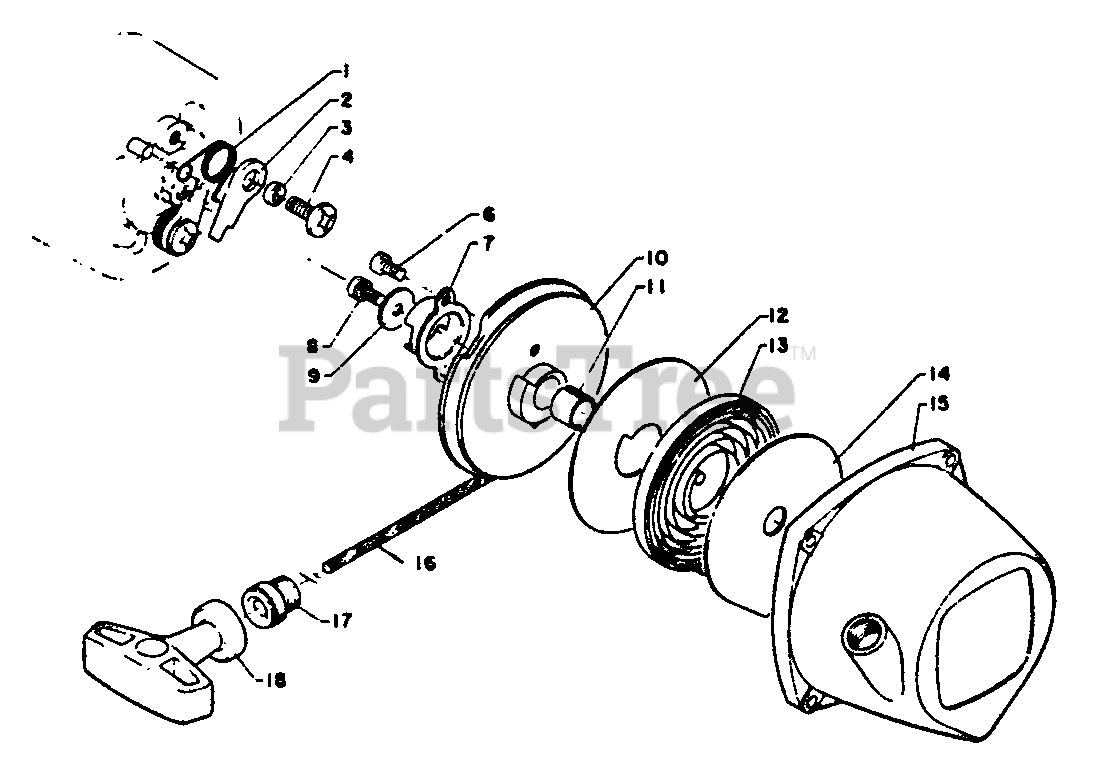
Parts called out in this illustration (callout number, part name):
1	SPRING, RETURN
2	PAWL, STARTER
4	SCREW
6	SCREW - 4X8
7	CATCHER, PAWL
8	SCREW - 4X8
10	REEL, ROPE
12	PLATE, STARTER
13	SPRING, REWIND
14	PLATE, STARTER
15	CASE, STARTER
16	ROPE, STARTER - 3.5X850
17	GUIDE, ROPE
18	GRIP, STARTER
